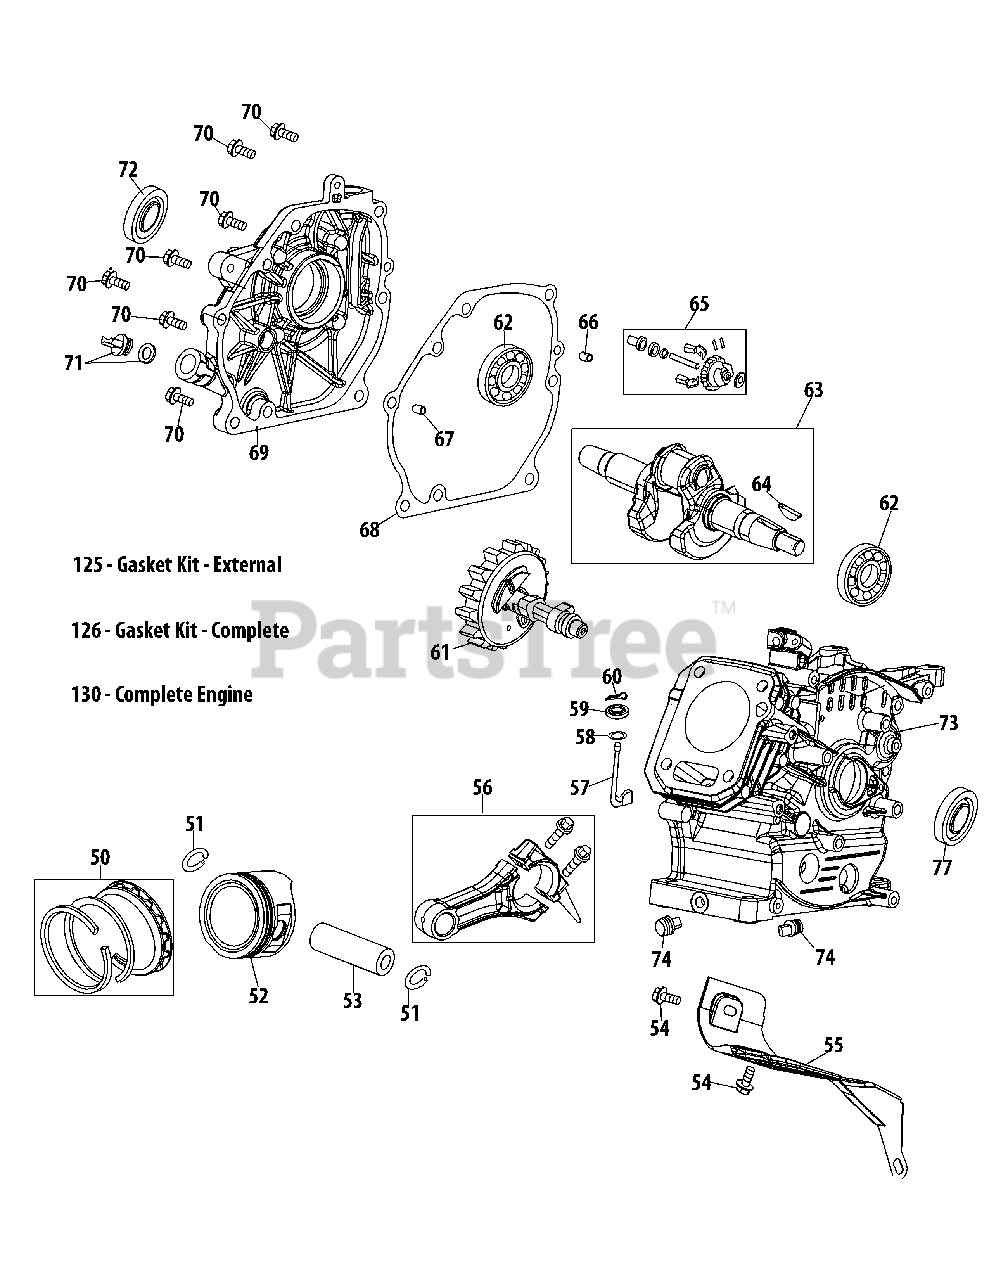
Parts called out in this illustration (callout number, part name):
50	Piston Ring Set
51	Piston Pin Snap Ring
53	Piston Pin
54	Bolt M6×12
55	Air Shield
56	Connecting Rod Assembly
57	Governor Arm Shaft
58	Washer 5.2×1.9
59	Governor Seal
60	Cotter Pin
61	Camshaft Assy.
62	Radial Ball Bearing, 6205
63	Crankshaft Assembly
64	Woodruff Key
65	Governor Gear/Shaft Assembly
66	Dowel Pin 7×14
67	Dowel Pin 9×14
68	Crankcase Cover Gasket
69	Cover Comp, Left Crankcase
70	Bolt M8×32
72	Oil Seal, 25×41.25×6
73	Short Block
74	Oil Drain Plug
77	Oil Seal 25×41.25×6
125	Gasket Kit - External
126	Gasket Kit - Complete
130	Complete Engine
